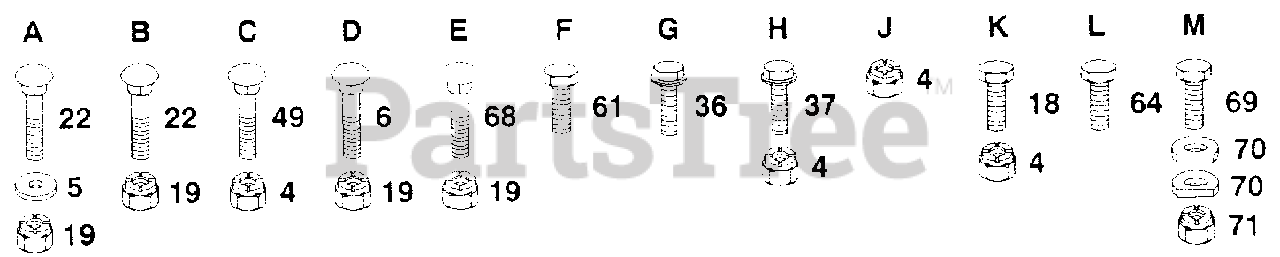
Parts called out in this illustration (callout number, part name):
5	WASHER M
6	BOLT
22	BOLT
36	SCREW
37	SCREW
49	BOLT
61	BOLT
64	BOLT.3/8-14X1.25
69	BOLT LT
70	WASHER T
